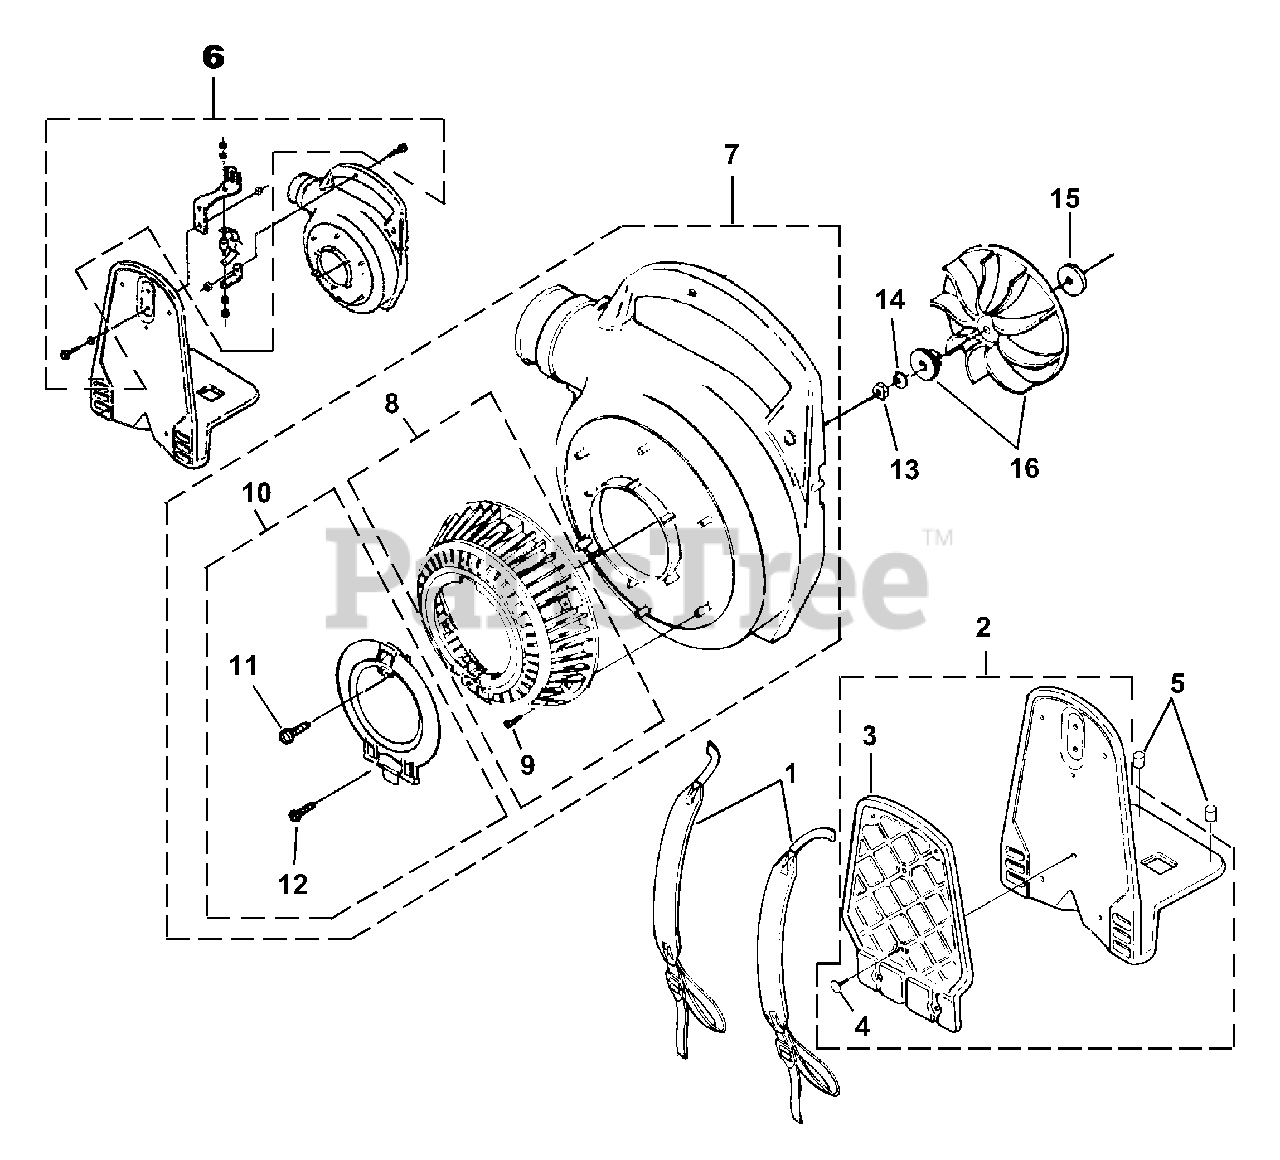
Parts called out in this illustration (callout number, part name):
1	HARNESS-Shoulder
2	FRAME-Blower
3	PAD-Foam
4	CLIP-Push
5	VIBRATION ISOLATOR
6	VIBRATION ISOLATOR KIT
7	VOLUTE HOUSING KIT
8	BLOWER VAC GRILLE KIT
9	SCREW-Thread Form. (#6 X 3/8")
10	ACCESS DOOR KIT
11	SCREW-Thread Rolling (#10 X 5/8")
12	SCREW-Thread Form. (#8 X 1/2")
13	NUT-Hex (3/8-24)
14	WASHER-Bellville (3/8")
15	WASHER-Flat
16	BLOWER FAN KIT
